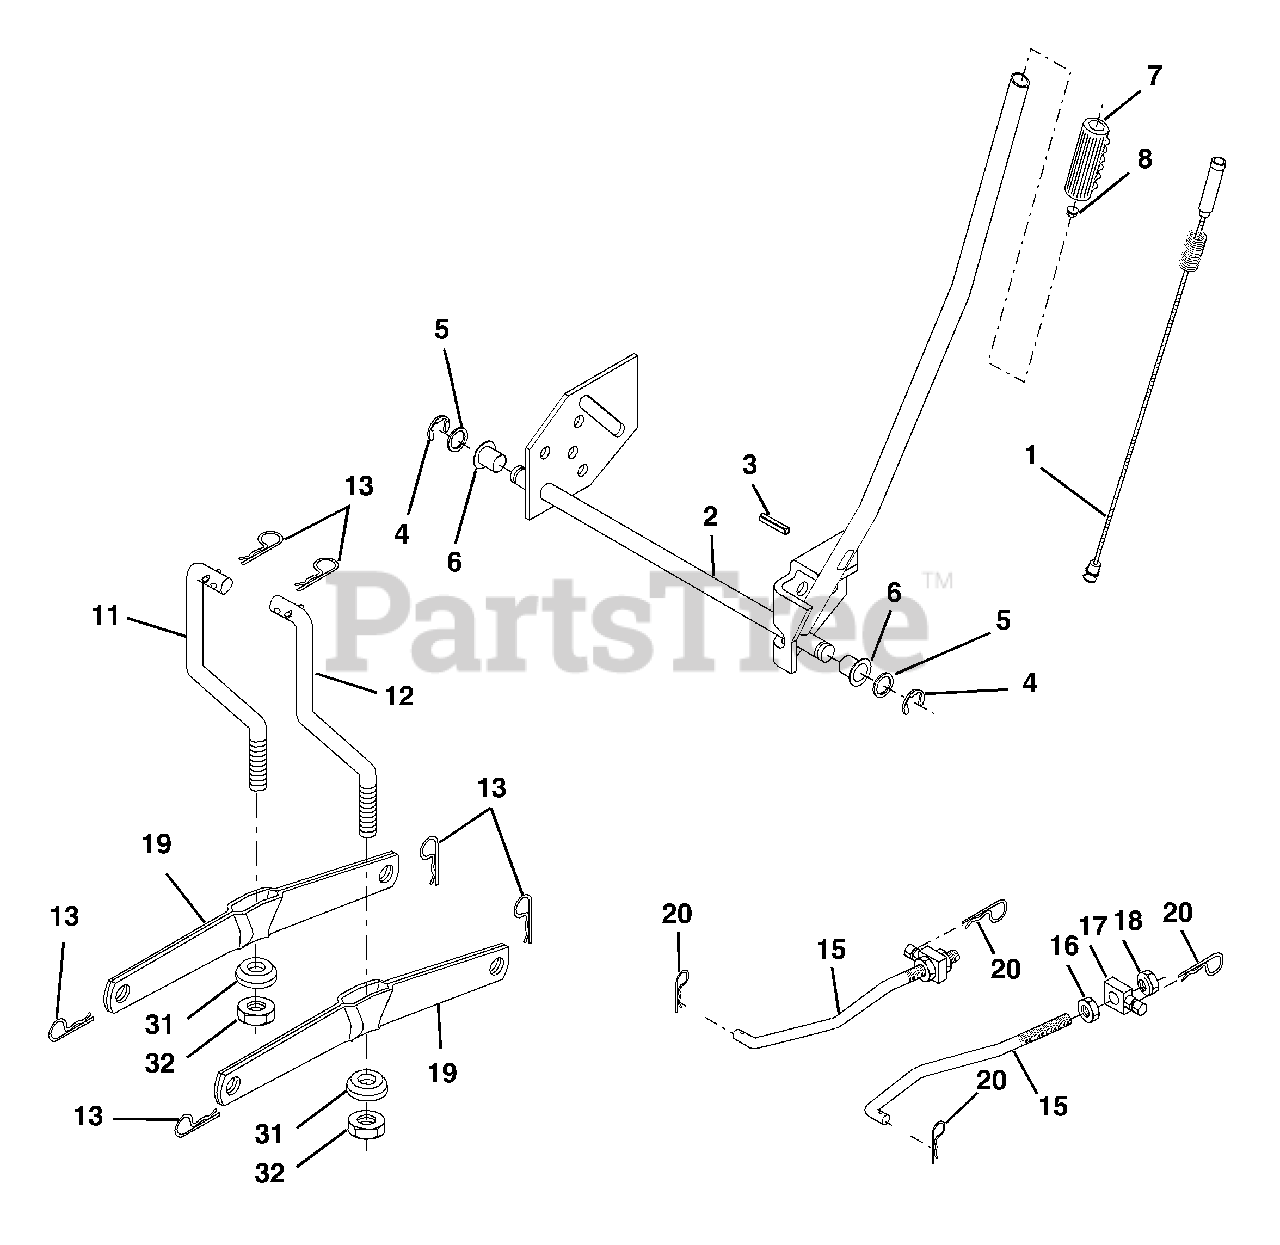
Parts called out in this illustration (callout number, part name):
1	Wire Asm Inner/Sprg w/plunger
2	Shaft Asm Lift RH
3	Pin Groove
4	E Ring #5133-62
5	Washer 21/32 x 1 x 21 Ga.
6	Bearing Nylon Blk 629 Id
7	Grip Handle Bicycle Matte Blk
8	Button Plunger Black
11	Link Lift LH Fixed Length
12	Link Lift RH Fixed Length
13	Retainer Spring
15	Link Front
16	Nut Jam Hex 1/2-13 unc
17	Trunnion
18	Nut Lockw/Wsh 1/2-13 unc
19	Arm Suspension Rear
20	Retainer, Spring
31	Bearing Pvt Lift
32	Nut Crownlock 3/8-24
